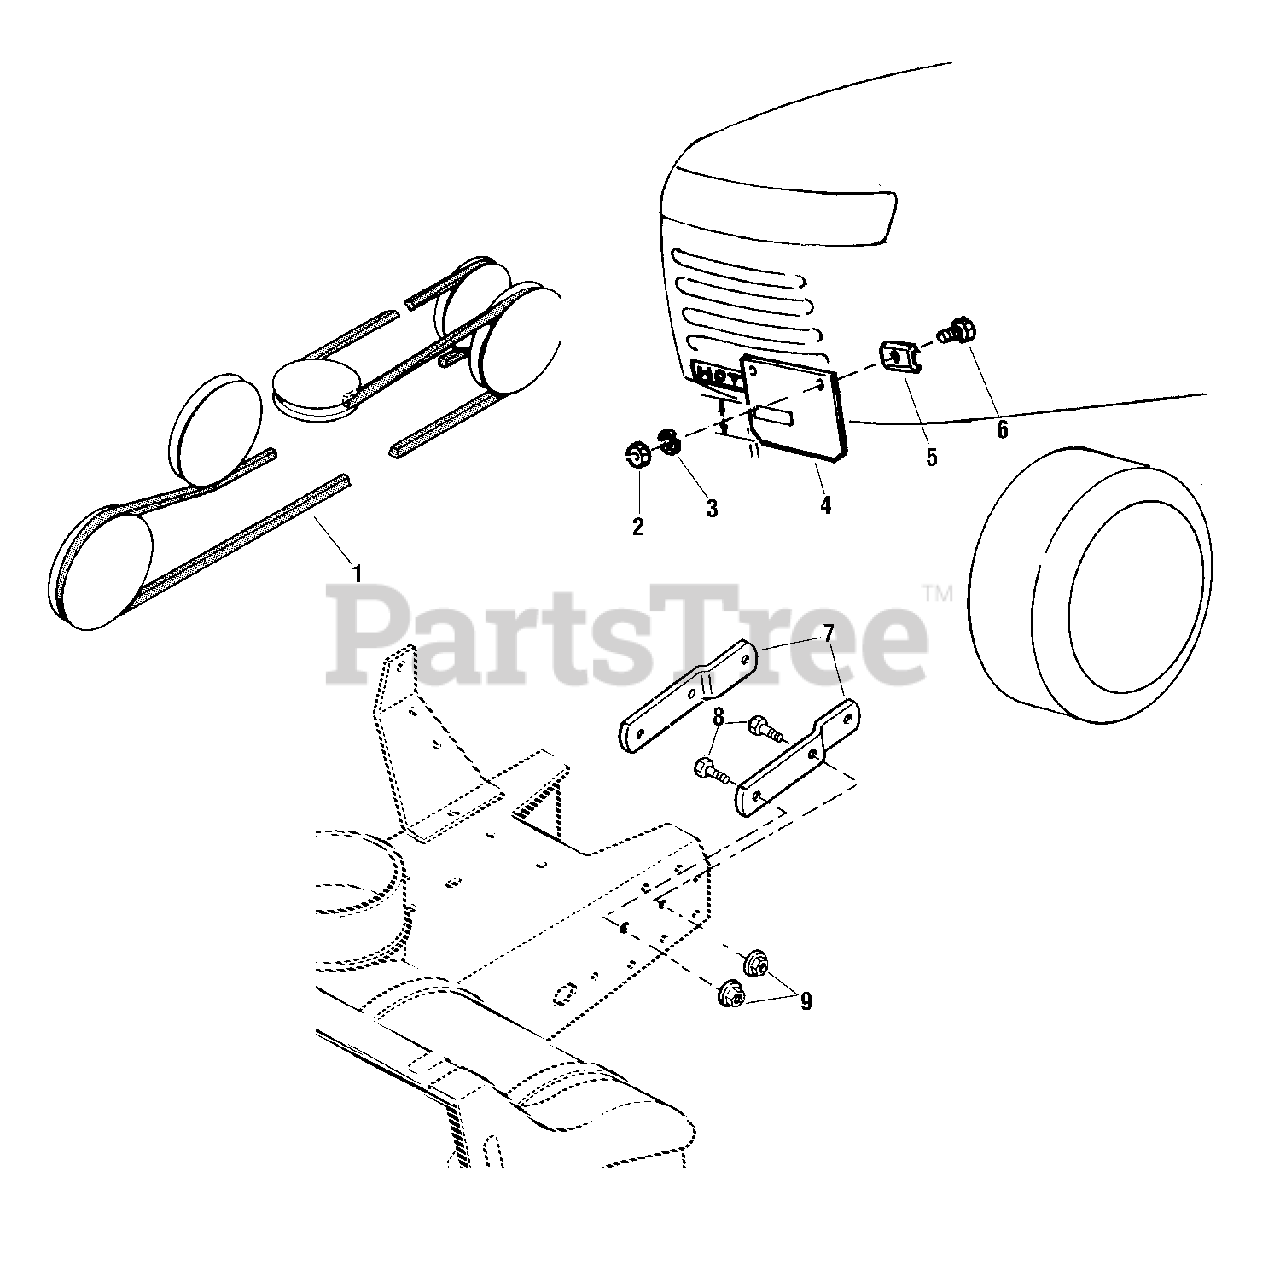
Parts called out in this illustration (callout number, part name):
2	NUT, Hex, 1/4-20
3	LOCKWASHER, 1/4
4	PLATE
6	CARRIAGE BOLT, 1/4-20 x 7/8
8	CAPSCREW, Hex Head, 7/16-14 x 1
9	NUT, Hex, Flange Lock, 7/16-14
